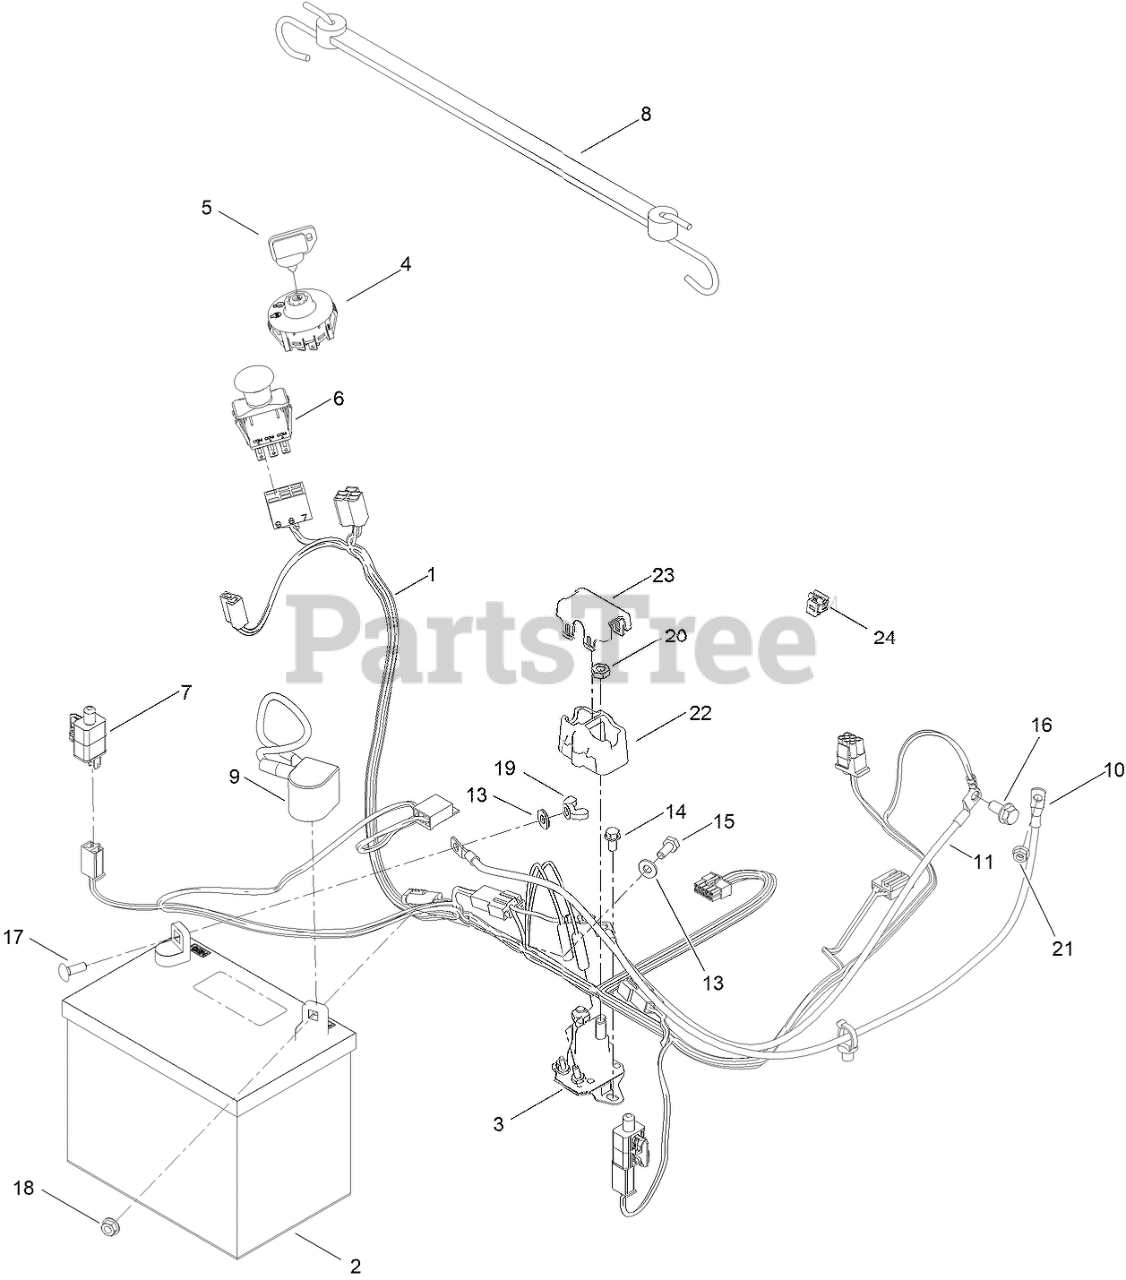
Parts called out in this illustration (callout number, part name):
1	HARNESS-WIRE
2	BATTERY
3	SOLENOID
4	SWITCH-IGNITION
5	KEY-IGNITION
6	SWITCH-PTO
7	SWITCH
8	STRAP-RUBBER
9	CABLE-BATTERY, POS
10	CABLE-BATTERY, RED (8 GAUGE)
11	CABLE-BATTERY, BLACK
13	WASHER-FLAT
14	SCREW-HWH
15	SCREW-HH
16	SCREW-HHF
17	BOLT-CARR
18	NUT-HF
19	NUT-WING
20	NUT-JAM
21	NUT-HF
22	COVER-SOLENOID
23	CAP-SOLENOID
24	CLIP-HARNESS
